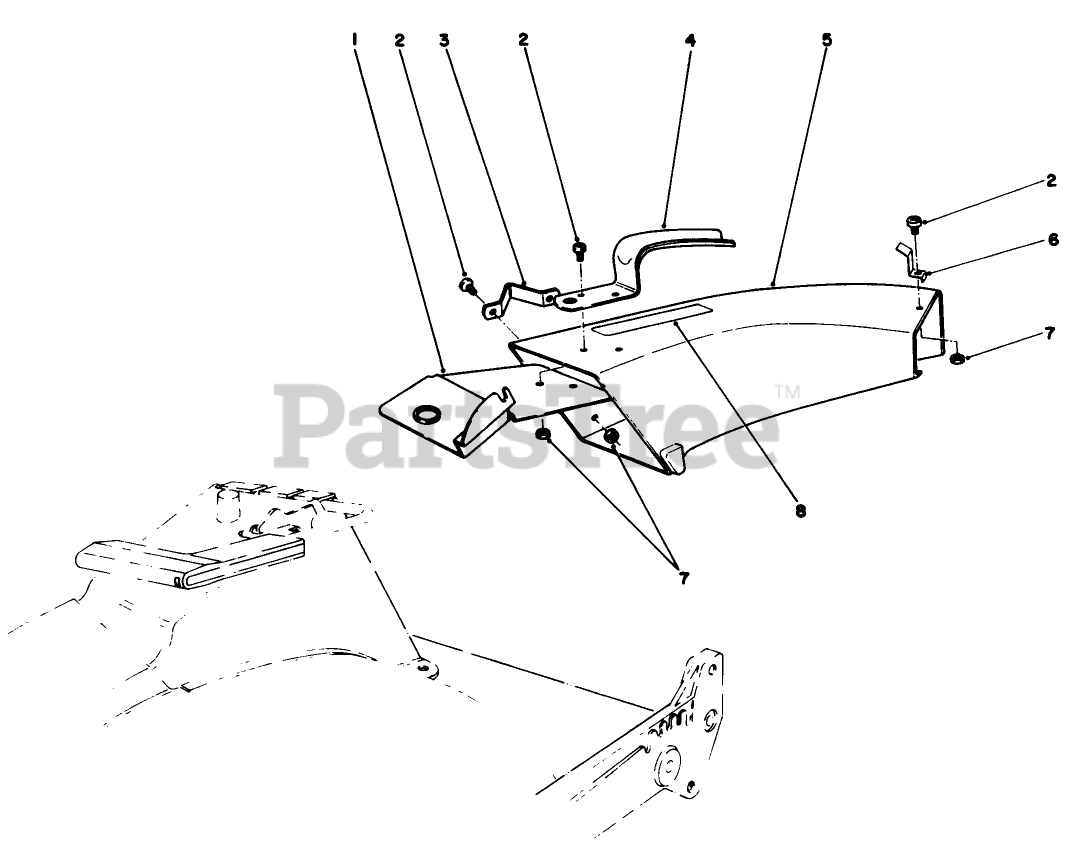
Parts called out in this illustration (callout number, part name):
2	10-24 X 5/8 PAN HD MS
4	CHUTE HANDLE
5	ORDER 59168 W.G.#
7	NUT-LOCK, NI
